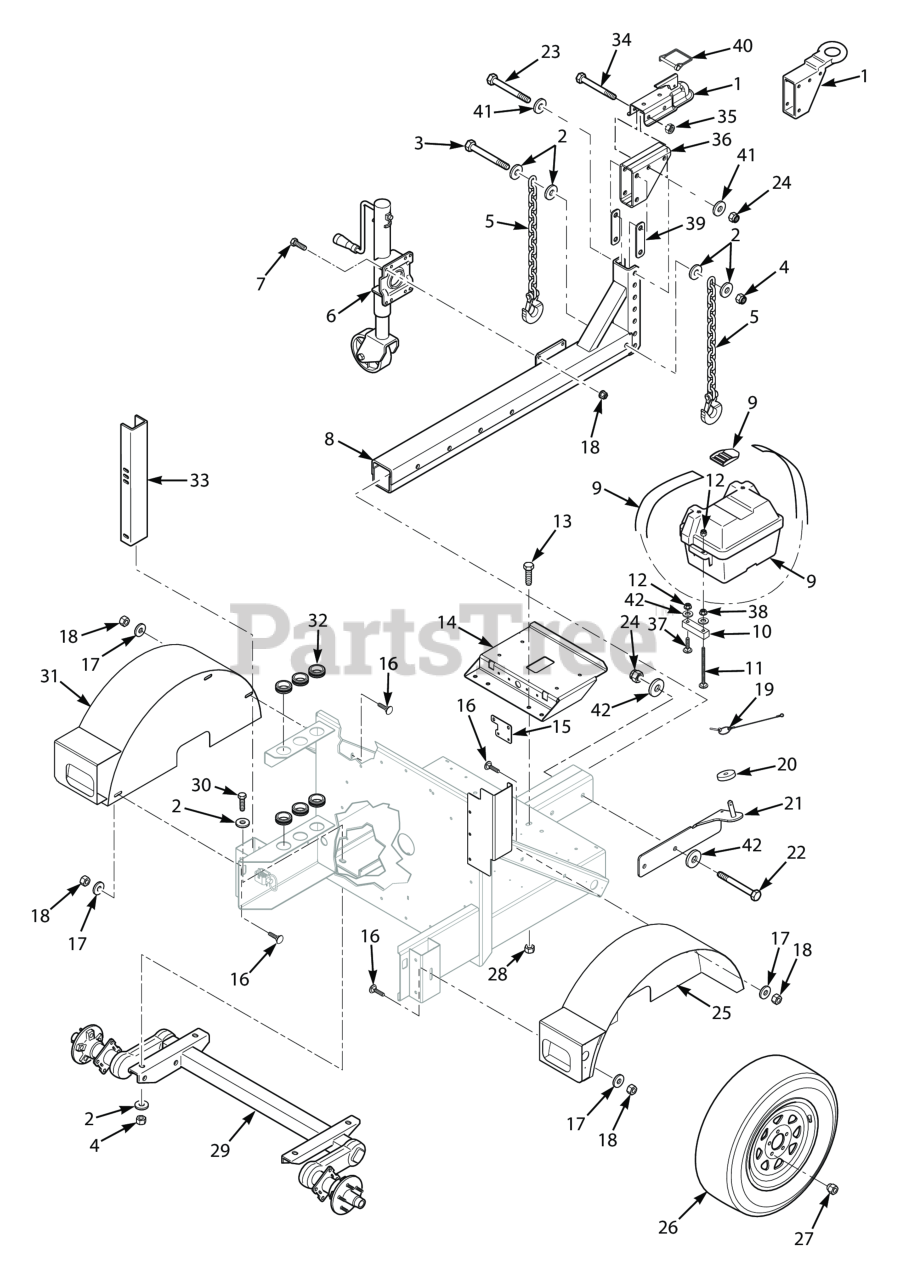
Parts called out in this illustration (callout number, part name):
1	Ball Hitch, 2"
2	Flatwasher, 1/2 - .531 x 1.062 x .095
3	HHCS, M12-1.75 X 140 LG
4	LKNUT, M12-1.75 ELAS STOP
5	Safety Chain
6	Jack, Single Wheel
7	Bolt, Hex Head, 3/8-16 x 1 Gr. 5
8	Draw Bar Assembly w / Decals (INCL. 1,2,3,4,5,6,7,17,23,24,34,35,36,39,40,41,Decal-485126)
9	Battery Box w/Strap
10	Spacer, Battery Bob (x6)
11	Bolt, Carriage 1/4-20 x 6"
12	HEX, NUT, ELASTIC STOP LOCK, 1/4-20
13	Bolt, Hex Head 1/2-13 x 1-1/4"
14	Fuel Tank Mount
15	Bracket, Cannister Mount
16	Carriage Bolt, 3/8-16 x 1.0"
17	Flatwasher, 3/8" Special (.391 x .938 x .105)
18	HEX NUT, ELASTIC STOP LOCK, 3/8-16
19	Quick Pin Assembly w/Lanyard
20	Washer, Rubber
21	Weldment, Hose Holder
22	BOLT, HEX HEAD, 5/8-11 X 5-1/2
23	Bolt, Hex Head 5/8-11 x 5" Grade 8
24	HEX LOCKNUT, ELASTIC STOP, 5/8-11
25	Fender Weldment, RH
26	Wheel Assembly, 205/75D15 - 6 Ply
27	Wheel Nut, 1/2-20 x 13/16
28	Nut, Hex Serrated Flange 1/2-13
29	Axle, 2000 LBS - 5 Lug, 47"
30	Bolt, Hex Head 1/2-13 x 1-1/2", (STT-52 & STTII-52)
31	Fender Weldment, LH
32	Grommet, Rubber
33	Support Channel
34	Bolt, Hex Head 1/2-13 x 3-1/2"
35	HEX LOCKNUT, ELASTIC STOP, 1/2-13
36	Ball Hitch Mount
37	Bolt, Carriage 1/4-20 x 6"
38	NUT, 1/4-20 SERRATED FLANGE HEX HEAD
39	Plate, Spacer
40	Pin, Snapper
41	Flatwasher, 5/8" (.656 x 1.312 x .095")
42	Flatwasher, 1/4" (.312 x .750 x .065")
